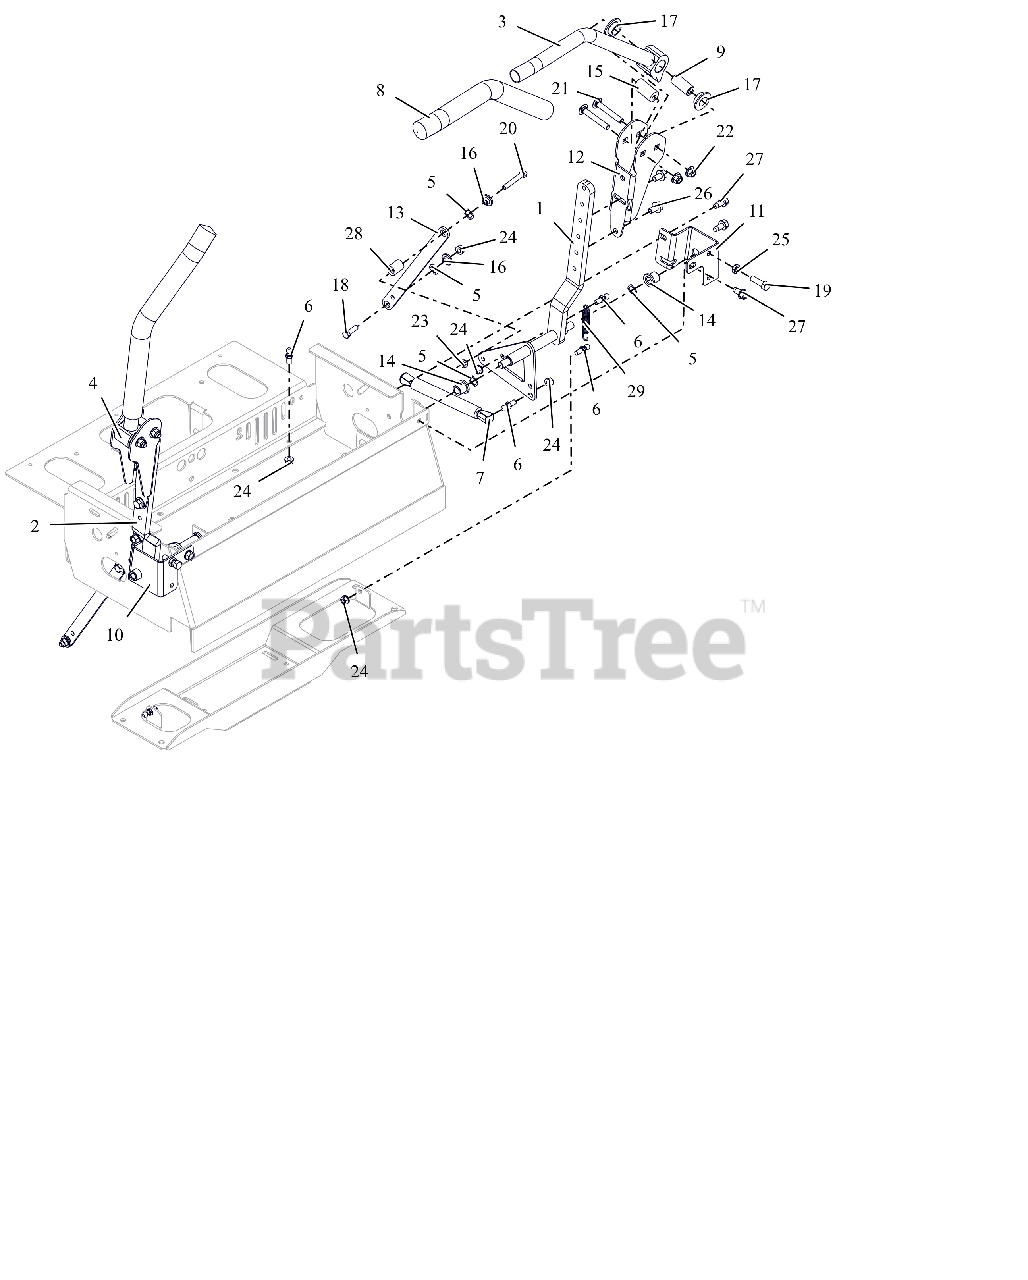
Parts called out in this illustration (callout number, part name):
1	WLDMT, LH LOWER CONTROL ARM
2	WLDMT, RH LOWER CONTROL ARM
3	WLDMT, CONTROL HANDLE-LH (BLACK)
4	WLDMT, CONTROL HANDLE-RH (BLACK)
5	WAVE WASHER .531X.781X.125FH
6	STUD- BALL
7	DAMPER
8	GRIP, HANDLEBAR
9	SPACER, STEERING ARM
10	PT200/400 RH CNTRL STP BRK-RED
11	PT200/400 LH CNTRL STP BRK-RED
12	ADJ UPPER CONTROL ARM BRKT-BLK
13	LINK, STEERING CONTROL
14	BHSG-FLG .500X.750X.750X.125
15	BSHG, ECCENTRIC.406X.875X1.625
16	BSHG-FLG .32X.500X.344X.880
17	BSHG-FLG .762X1.48X.44 NYL
18	BLT,HEX .31-18X1.00 G5 ZCC
19	BLT, HEX .38-16X1.25 G5 ZCC
20	BLT, HEX .31-18X2.00 G5 ZCC
21	BLT, RHSSN.38-16X2.50 G5 ZCC
22	NUT,NYL-FLG .38-16 GF ZCC
23	NUT,LK-CTR .31-18 GA ZCC
24	NUT-LK-TOP-FLG .312-18 GF ZCC
25	NUT-JAM .375-16 G2 ZCC
26	BLT, SERHFWH .38-16X.625 ZCC
27	SCR,TAP .375-16X.75 HWH TR ZCC
28	ECCENTRIC
29	SPRING,EXT,.061X.50X3.0
